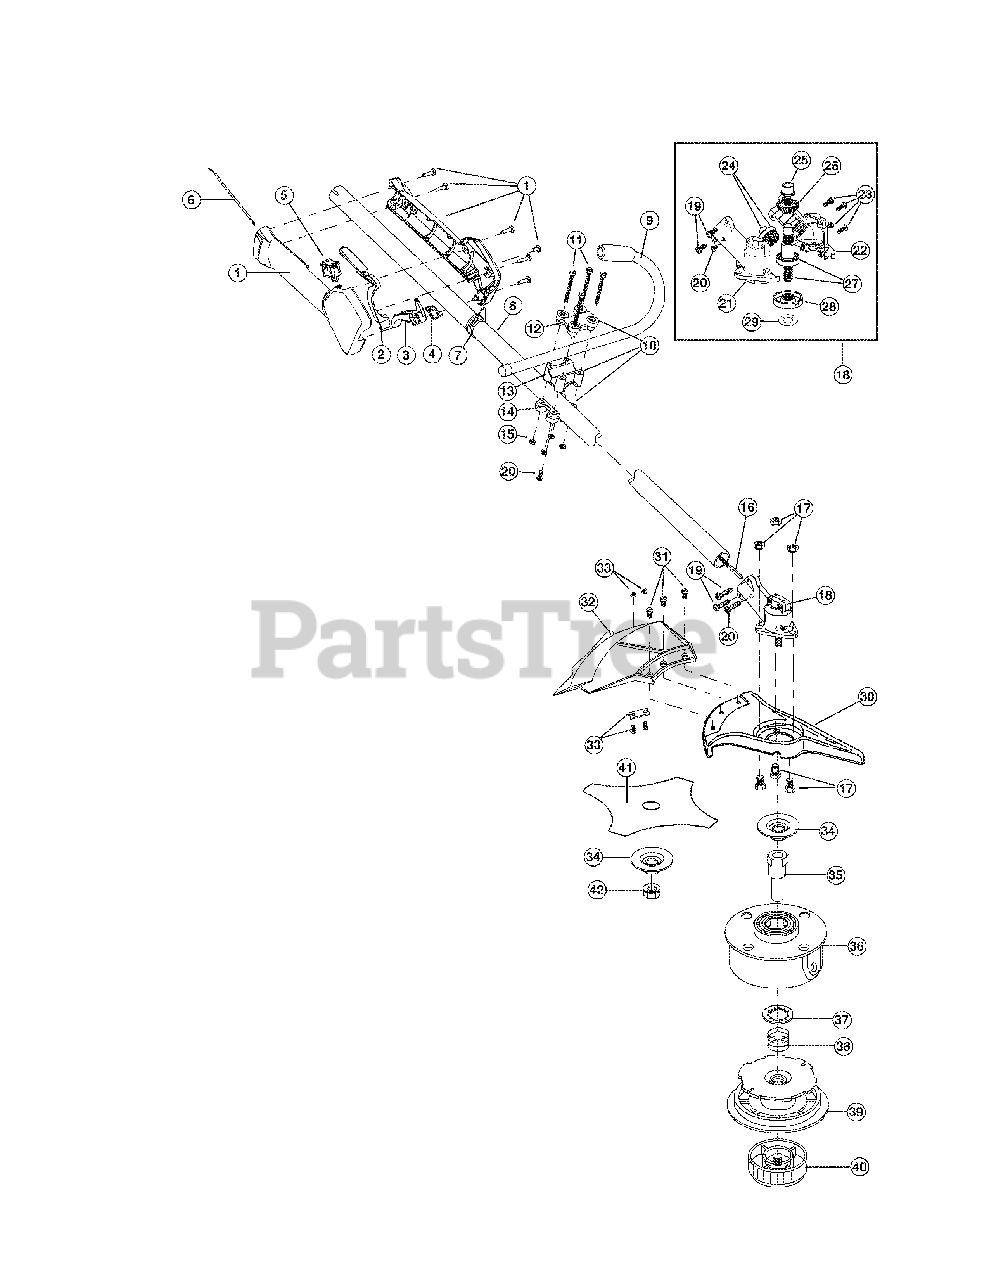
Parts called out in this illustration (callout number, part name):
1	Throttle Housing Assembly (includes 2-4)
2	Throttle Trigger Lock-Out
3	Throttle Trigger
4	Throttle Trigger Spring
5	Switch Assembly (includes 6)
6	Throttle Cable Assembly
7	Harness Clip
8	Upper Drive Shaft Housing Assembly
9	J-Handle Assembly
10	Handle Bracket Assembly (includes 13-15 & 20)
12	Upper Handle Clamp
13	Middle Handle Clamp
14	Lower Handle Clamp
16	Flexible Drive Shaft
17	Shield Mount Screw Assembly
18	2 piece Gearbox Assembly (includes 19-29)
19	Gearbox Mounting Hardware
20	Anti-Rotation Screw
21	Left Housing
22	Right Housing
23	Gear Box Screw
24	Pinion Gear Assembly
25	Output Shaft Bushing
26	Output Shaft Gear
27	Output Shaft Assembly (includes 25 & 26)
28	Blade Driver
29	Palnut
30	Blade Shield/Shield Mount
31	Shield Mounting Screw
32	Shield Assembly (includes 33)
33	Blade Assembly
34	Retaining Washer
35	Spool Shaft
36	Outer Spool Assembly
37	Retainer
38	Spring
39	Inner Reel
40	Bump Head Knob Assembly
41	4-Tooth Blade
42	Nut
